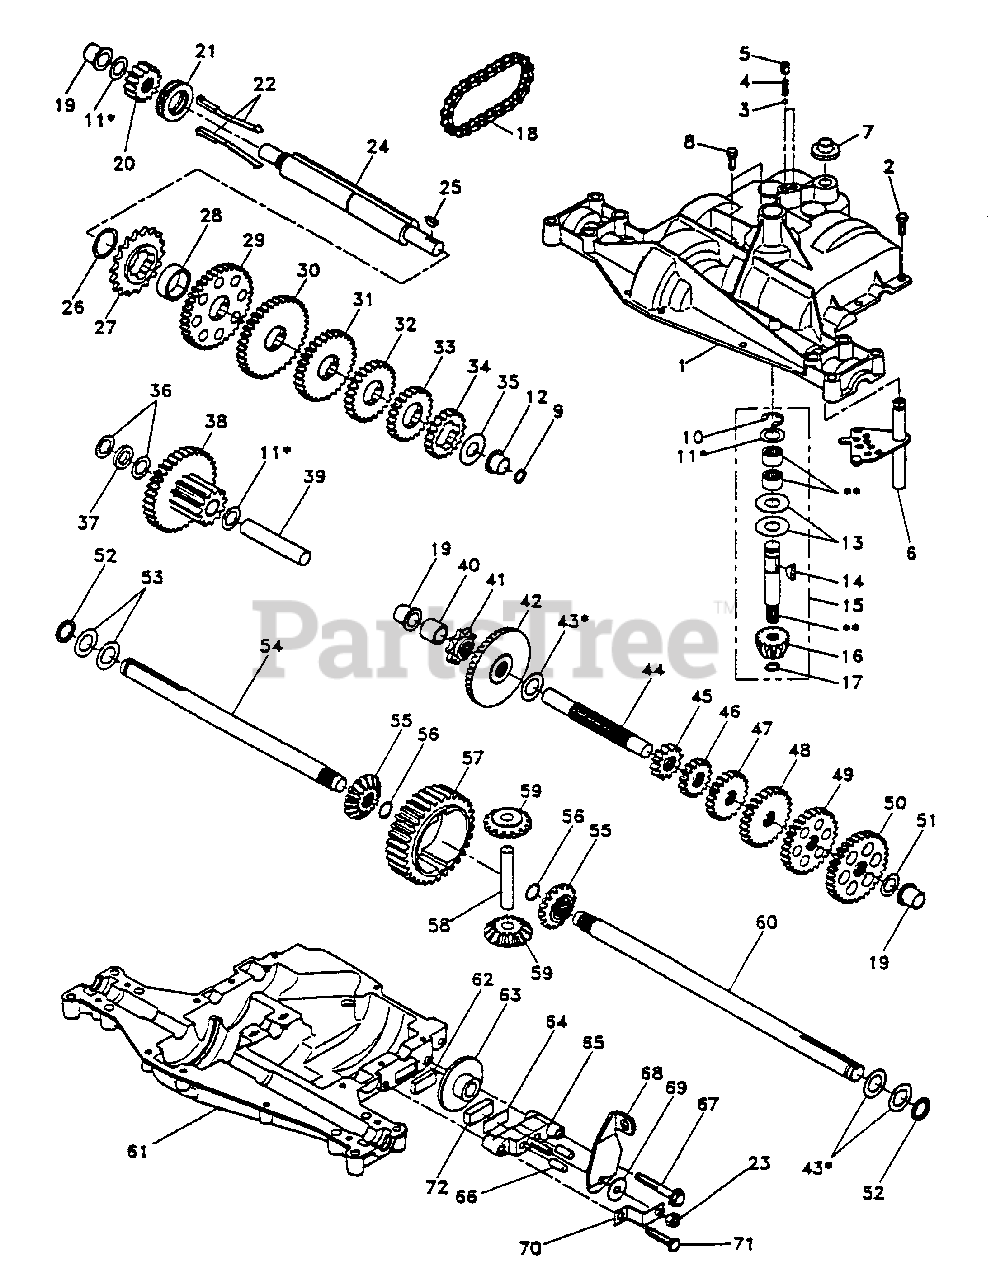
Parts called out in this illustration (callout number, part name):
1	Housing, Upper
2	Screw, Self-Tapping, Large 1/4-20 x .734
3	Ball, Detent
4	Spring, Detent
5	Screw, Set
6	Kit, Shifter Assembly
7	Boot, Shifter
8	Screw, Tapping w/Sealer
9	Square Ring
10	Ring, Retaining
11	Assembly, Kit, Shim .625 Shaft
12	Bearing, Flange
13	Washer, Plain .632 x 1.38 x .046
14	Key, Woodruff, #9
15	Assembly, Kit, Input Shaft
16	Pinion, Bevel, 14 Teeth
17	Ring, Retaining
18	Chain, 24 Pitches
19	Bearing, Flange
20	Gear, Spur, 14 Teeth
21	Collar, Clutch
22	Assembly, Kit, Clutch Keys
23	Locknut 5/16-24
24	Shaft, Intermediate
25	Key, Woodruff, #61
26	Ring, Retaining
27	Sprocket, 18 Teeth
28	Spacer
29	Gear, Spur, 37 Teeth
30	Gear, Spur, 35 Teeth
31	Gear, Spur, 30 Teeth
32	Gear, Spur, 25 Teeth
33	Gear, Spur, 22 Teeth
34	Gear, Spur, 19 Teeth
35	Washer, Plain .640 x 1.37 x .061
36	Washer, Plain .632 x 1.00 x .026
37	Spacer .630 x 1.00 x .169
38	Assembly, Gear, Combination of 12 Teeth and 35 Teeth
39	Shaft, Idler
40	Spacer .635 x .875 x .755
41	Sprocket, 9 Teeth
42	Gear, Bevel, 42 Teeth
43	Assembly, Kit, Shim .750 Shaft
44	Shaft, Drive
45	Gear, Spur, 12 Teeth
46	Gear, Spur, 15 Teeth
47	Gear, Spur, 20 Teeth
48	Gear, Spur, 25 Teeth
49	Gear, Spur, 28 Teeth
50	Gear, Spur, 31 Teeth
51	Washer, Plain .632 x 1.00 x .060
52	Washer, Neoprene
53	Washer, Plain .758 x 1.25 x .031
54	Axle, L.H.
55	Gear, Miter, 15 Teeth
56	Ring, Retaining
57	Gear, Spur, 32 Teeth
58	Shaft, Cross
59	Gear,-Miter, 15 Teeth
60	Axle, R.H.
61	Housing. Lower
62	Puck, Friction
63	Disc, Brake
65	Jaw, Brake
66	Pin, Dowel
67	Screw, Self-Tapping, Large 5/16-18 x 2.25
68	Lever, Actuating
69	Washer, Plain .321 x 1.00 x .055
70	Bracket, Anti-Rotation
71	Screw, Self-Tapping, Large 5/16-18 x 1.44
72	Puck, Friction
